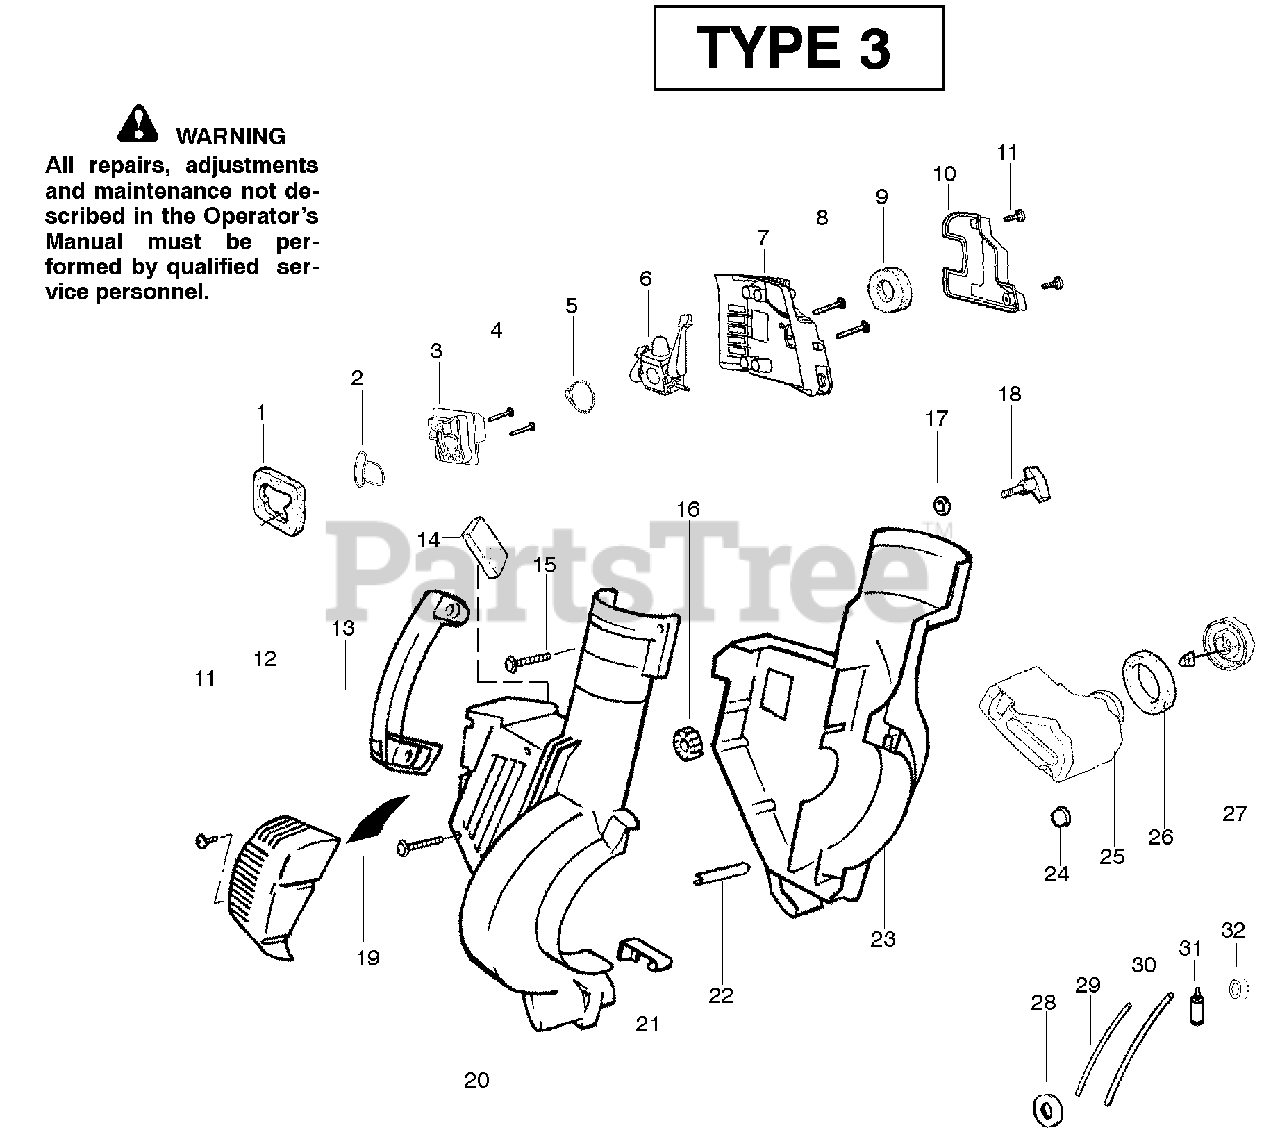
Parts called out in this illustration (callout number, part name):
1	Air Dam (kit)
2	Gasket-Adapter (kit)
3	Carburetor Adaptor
5	Gasket-Carburetor (kit)
6	Kit-Carb Ass'y. (C1Q-W11)
6	Kit-Carb Ass'y. (C1Q-W11C)
10	Cover-Air Filter
12	Guard-Muffler
14	Foam - 71.12mm (kit)
18	Knob-Tube Clamp
19	Reflector-Heat (kit)
20	Assy-Housing-Right
21	Spring-Cover Latch
22	Guide-Starter Rope
24	Isolator-Crankcase
25	Assy-Fuel Tank
26	Gasket-Fuel Tank
27	Fuel Cap w/Retainer
28	Grommet-Shroud
29	Kit-Line Carb/Purge
30	Kit-Line Tank/Purge
31	Assy-Fuel Pick-up
32	Grommet-Fuel line (kit)
